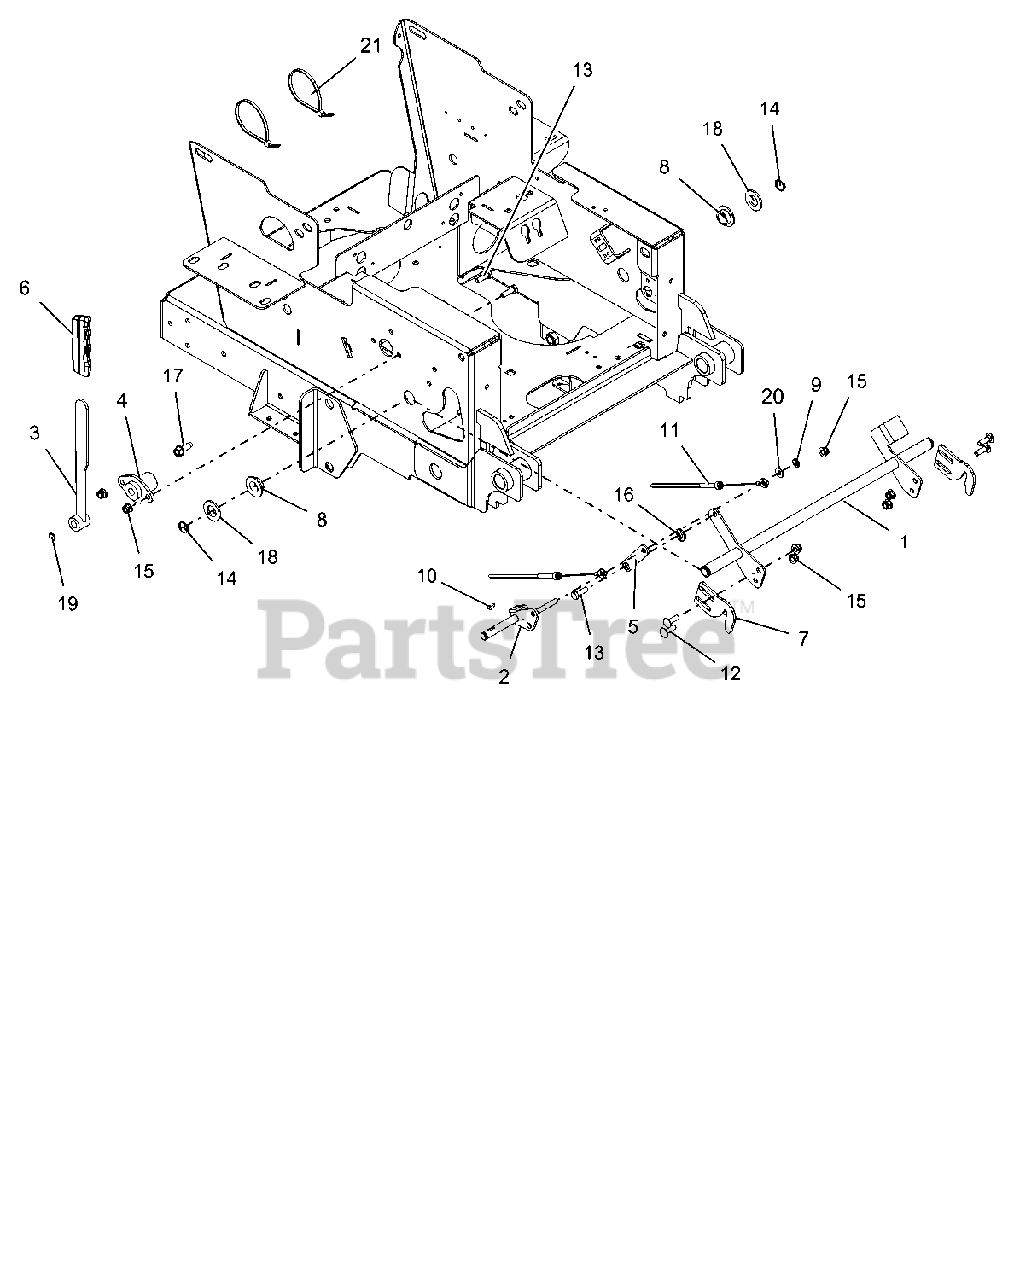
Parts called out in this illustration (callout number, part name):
1	WMT, NEUTRAL INTERLOCK
2	WMT, PARK BRAKE ARM
3	WMT - PARKING BRAKE ARM
4	BUSHING, FLANGED
5	PLATE, NEUTRAL INTERLOCK
6	GRIP, PARKING BRAKE (YELLOW)
7	NEUTRAL LOCK LATCH - BLACK
8	BSHG-FLG .762X1.48X.44 NYL
9	NUT-PUSH .312
10	KEY-WDRF .13X.63 HRD#5
11	CABLE, BRAKE ACTUATING
12	@BLT-RDHDSQNK .31-18X1.00 G5YZ
13	@BLT-HEX .31-18X1.00 GR5 YWZC
14	RG-RTNG-EXT .689X.078
15	@NUT-LK-NYL-FLG .31-18 YWZC
16	BSHG, FLG .325X.499X.26X.88
17	@SCR-TAP .38-16X1.00 HWH TR YZ
18	@WSHR-FL-STL.812X1.50X.135YWZC
19	RG-RTNG-EXT .500X.050 (SNAP)
20	@WSHR-FL-STL.344X.688X.065YWZC
21	CABLE TIE LG 5-1/2
